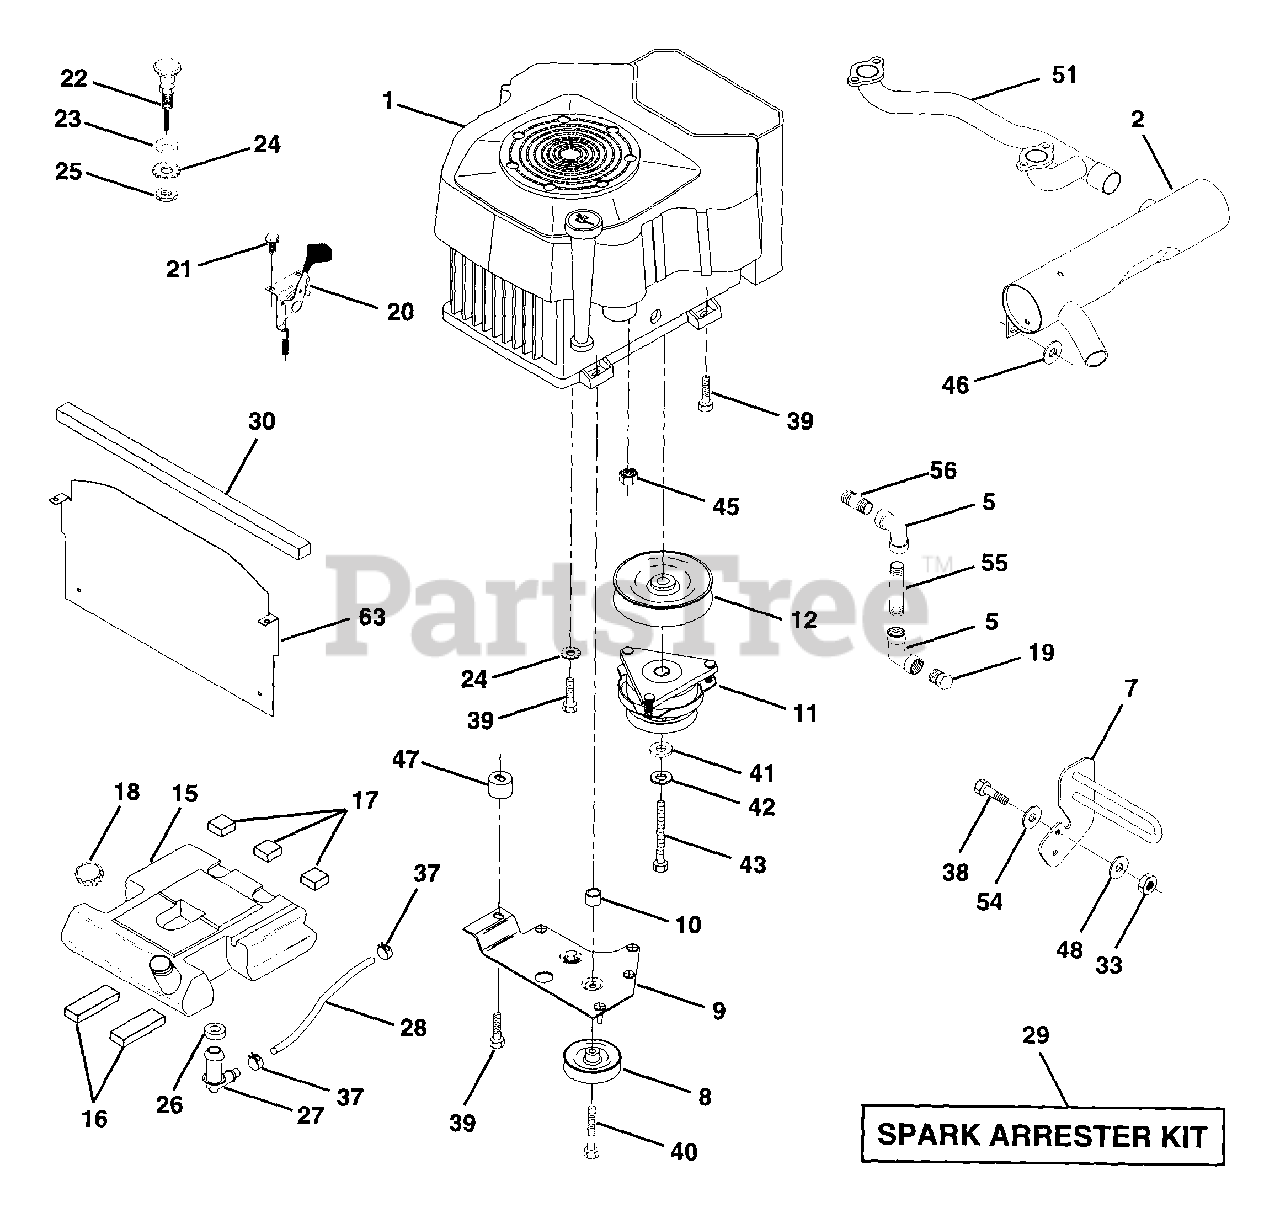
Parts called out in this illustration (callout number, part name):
2	Muffler VGT Cylinder
5	Elbow STD 90 Degree 3/8 - 18 NPT
7	Muffler Assembly Guard
8	Pulley V-idler
9	Stop Keeper Asm VGT
11	Clutch Electric
12	Pulley Engine VGT Elect Clutch
15	Tank Fuel W/Sym Vented
16	Pad Spacer
17	Pad Spacer
18	Cap Asm Fuel W/Sym Vented
19	Plug Oil Drain
20	Control Throttle
21	Screw Hex Thd Cut 1/4 - 20 X 5/8
22	Control Choke
23	Washer 13/32 X 13/16 x 16 Ga
24	Washer Ext Tooth 3/8
25	Nut Fin Hex 3/8 - 24 UNF
26	Bushing
27	Stem Tank Fuel
28	Fuel Line
29	Spark Arrester Kit
30	Strip Foam 18"
33	Nut, Hex W/Ins. 3/8-16 UNC
37	Clamp Hose
38	Bolt, Fin Hex 3/8-16 UNC x 1-1/2
39	Screw TT 3/8-16 x 2-1/4 UNC
40	Screw TT 3/8-16 x 4 UNC
41	Washer 1-1/2 OD X 15/32 ID X .250
42	Washer Lock 7/16
43	Bolt Hex 7/16-20 X 4-1/4 Ga 5
45	Nut, Flange 1/4-20 Starter Nut
46	Washer 13/32 x 1 x 16 Ga.
47	Spacer Engine CV22 Round PM
48	Washer 13/32 x 1-1/4 x 7 Ga.
51	Pipe Crossover CV22
54	Washer Flat 13/32 x 7/8 x 14 Ga.
55	Nipple, Pipe 3/8 N.P.T. x 4-1/2
56	Nipple, Pipe 3/8 NPT x 1.00
63	Shield, Heat VGT 22 HP YP/Husq.
